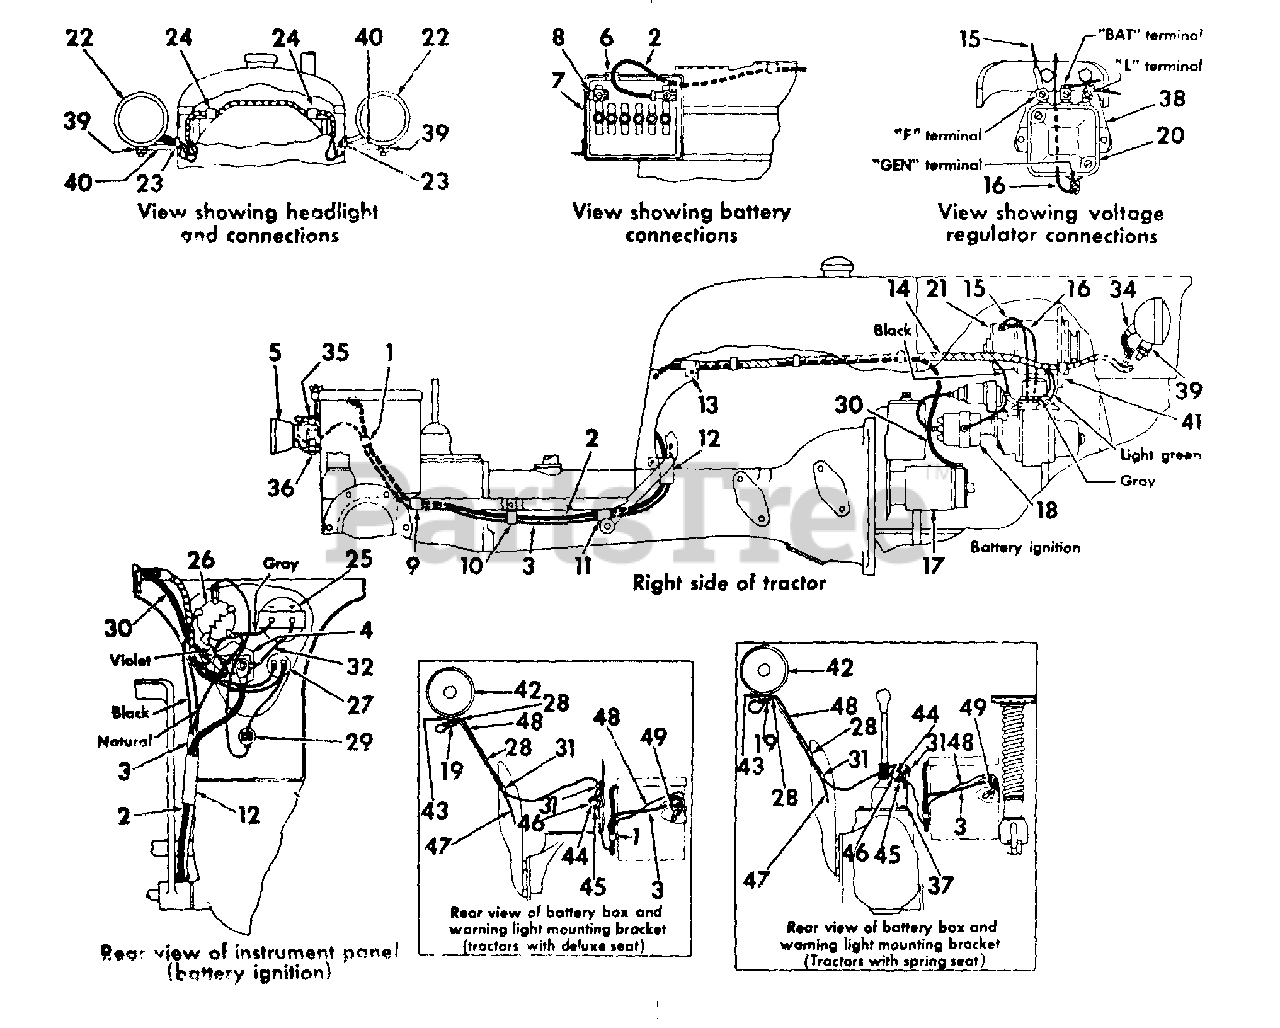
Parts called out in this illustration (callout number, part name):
1	STRAP, CABLE WRAPPING
2	CABLE, BATTERY TO STARTING SWITCH W/BOLT, IH-356062-R91
3	CABLE ASSY, REAR LIGHT
4	SWITCH ASSY, STARTING
5	LIGHT ASSY, TAIL
6	GROMMET, BATTERY BOX
7	BATTERY - 12 VOLT
8	STRAP, BATTERY TO GROUND W/BOLT, IH-356062-R91
9	CLIP, CABLE
10	CLIP, THIRD BOLT FROM REAR
11	STRAP, CABLE WRAPPING
12	CLIP, INSIDE RIGHT SIDE FUEL TANK SUPPORT
13	CLIP, CABLE HARNESS - RH SIDE
14	HARNESS ASSY, CABLE
15	CABLE, GENERATOR
16	CABLE, GENERATOR
17	MOTOR ASSY, CRANKING
18	BATTERY IGNITION UNIT
19	CLIP, FLASHING WARNING LIGHT CABLE
20	REGULATOR ASSY, VOLTAGE
21	GENERATOR ASSY
22	LIGHT ASSY, HEAD
23	GROMMET, RUBBER NO. 6
24	CLIP, HEAD LIGHT CABLE HARNESS
25	INDICATOR ASSY, CHARGE
26	SWITCH ASSY, LIGHTING
27	SWITCH ASSY, BATTERY IGNITION KEY
28	CLIP, SNAP-ON CABLE
29	HOUSING ASSY, FUSE
30	CABLE, BATTERY TO CRANKING MOTOR W/BOLT, IH-356062-R91
31	CLIP, FLASHING WARNING LIGHT CABLE
32	CABLE ASSY, STARTING SWITCH TO CHARGE INDICATOR -RED
34	BODY, CONNECTOR
35	CLIP, REAR LIGHT CABLE
36	CLIP, TAIL LIGHT CABLE
37	BRACKET, FLASHER MOUNTING CLAMP
38	BRACKET, VOLTAGE REGULATOR MOUNTING
39	SPACER, HEAD LIGHT
40	POST, HEAD LIGHT
41	CLIP, CABLE HARNESS
42	LIGHT ASSY, FLASHING WARNING
43	GASKET, FLASHING WARNING LIGHT
44	FLASHER ASSY, WARNING LIGHT
45	CLAMP, FLASHER MOUNTING
46	ABSORBER, FLASHER MOUNTING
47	BRACKET, FENDER MOUNTING
48	CABLE ASSY, FLASHER TO LIGHT
49	CABLE, FLASHING WARNING LIGHT TO LIGHTING SWITCH - BLACK
